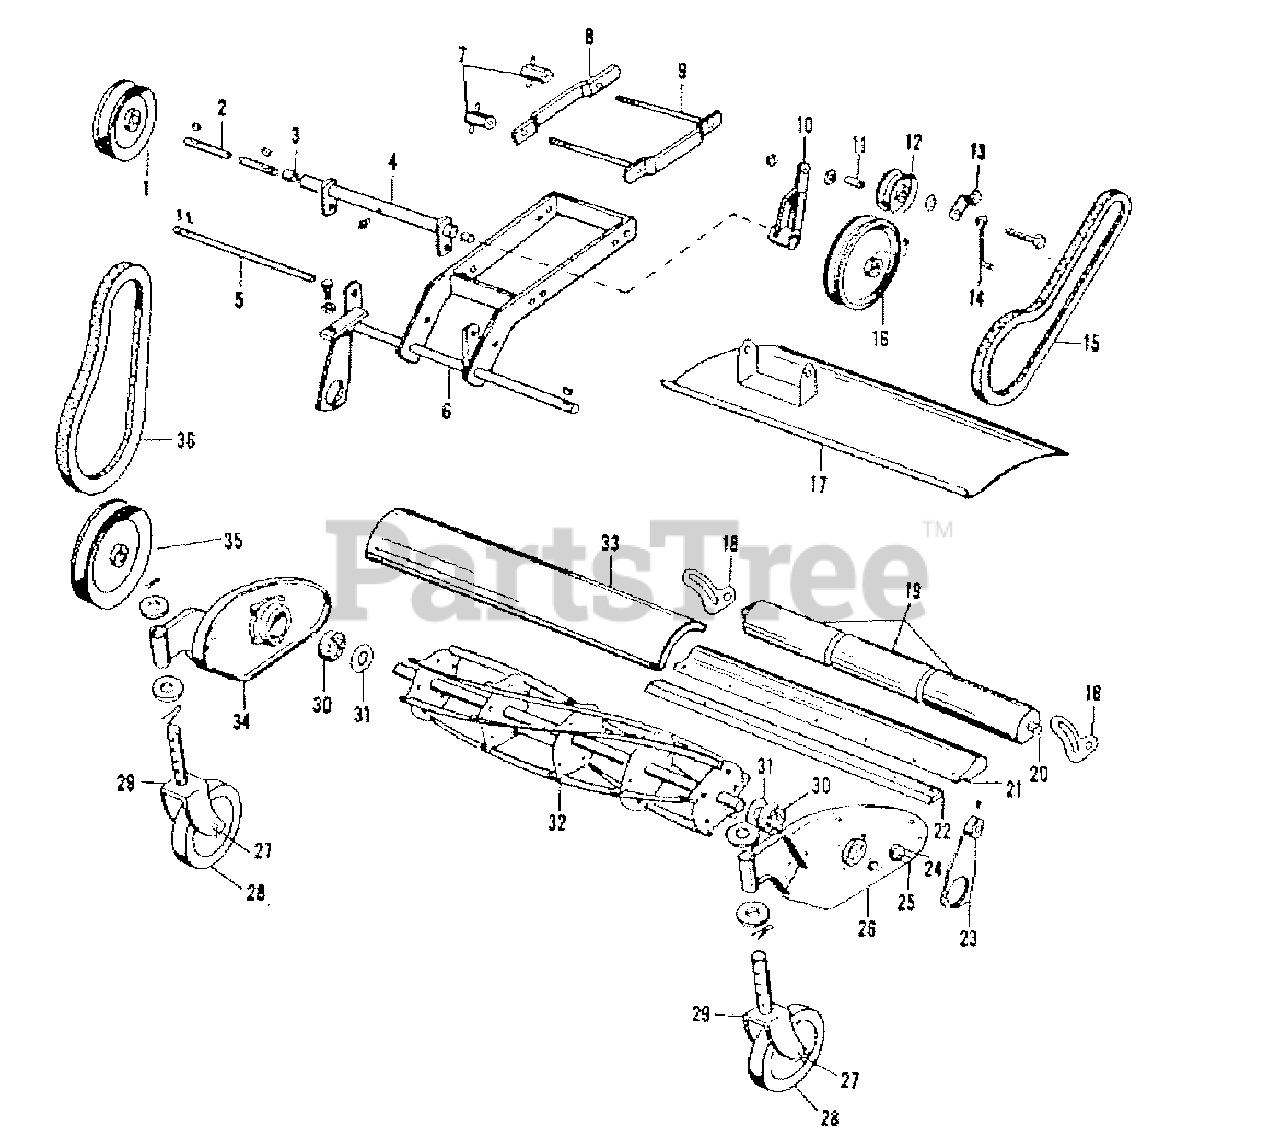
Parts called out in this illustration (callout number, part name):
2	PULLEY SHAFT
3	PULLEY SHAFT BEARING'
4	BEARING HOUSING ASSEMBLY
5	BEARING HOUSING ARM SHAFT
6	PUSH ARM ASSEMBLY
8	HITCH SIDE PLATE
9	HITCH CLAMP ASSEMBLY
10	IDLER LEVER ASSEMBLY
11	INNER BEARING RACE
12	IDLER PULLEY ASSEMBLY
14	BELT STOP
15	34" V BELT
16	DRIVE PULLEY
17	GRASS FENDER ASSEMBLY
18	ROLLER BRACKET
20	ROLLER SHAFT
21	CUTTER BAR
22	CUTTER BLADE BAR W/RIVETS
23	L.H. PUSH ARM ASSEMBLY
24	ADJUSTING CAM
25	CAPSCREW, Hex, Head 3/8-24 x 7/8
26	SIDE FRAME ASSEMBLY L.H.
27	CASTER AXLE
28	CASTER WHEEL w/BEARINGS
29	CASTER YOKE ASSEMBLY
30	BALL BEARING
31	REEL BEARING WASHER
32	REEL ASSEMBLY w/BEARINGS
33	BRUSH BAR
34	SIDE FRAME ASSEMBLY R.H.
35	SHEAVE--REEL
